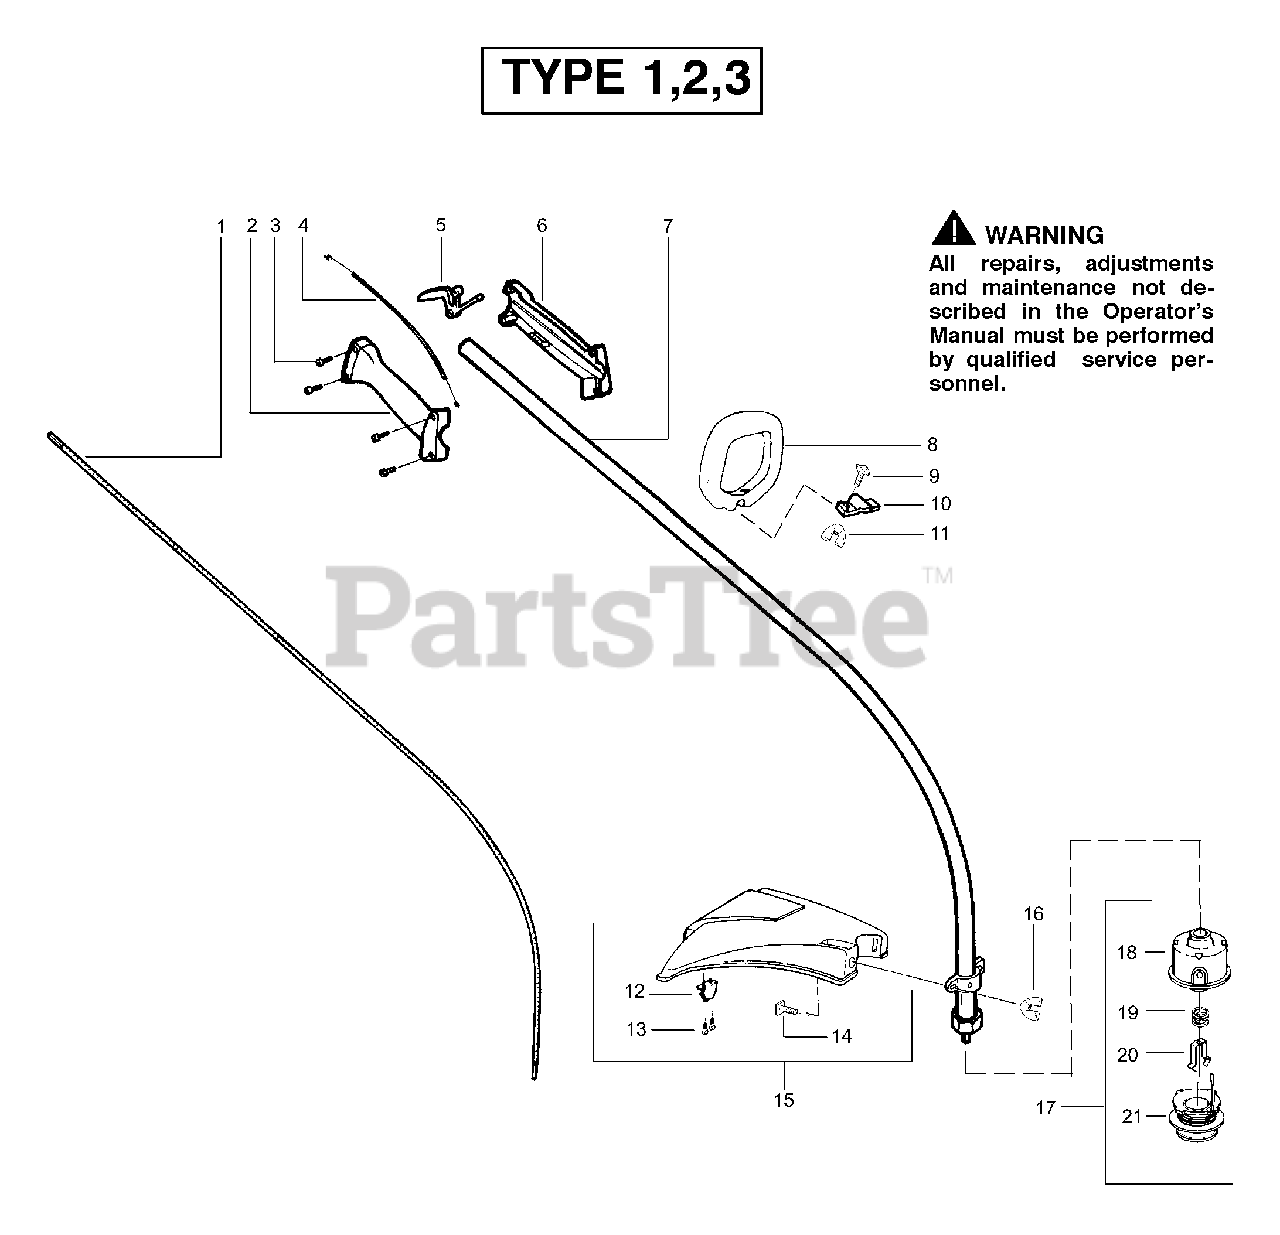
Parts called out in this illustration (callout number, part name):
1	Shaft Flex
2	Throttle Hsg. (Right)
3	Screw Throttle Hsg.
4	Assy Throttle Cable
6	Throttle Hsg. (Left)
7	Assy Drive Shaft Hsg.
8	Handle Assist
9	Bolt Handle/Shield
10	Clamp Handle
11	Wingnut Handle/Shield
12	Line Limiter
13	Screw Line Limiter
14	Bolt Handle/Shield
15	Kit Shield Assy
16	Wingnut Handle/Shield
17	Accy W/E TNG 5 Cutting Head
18	Assy Hub
19	Spring Compression
20	Clip Retainer Head
21	Accy W/E Spool w/Line
